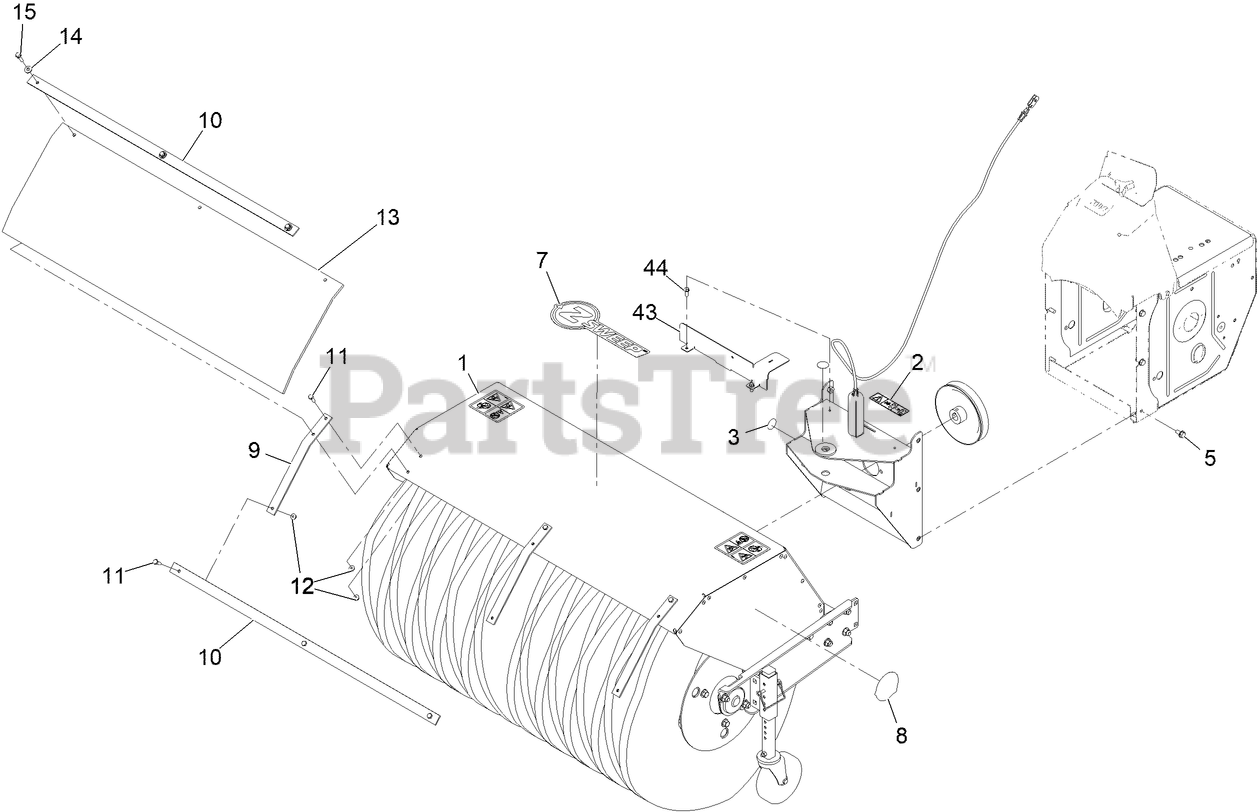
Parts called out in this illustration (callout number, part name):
1	Mb Broom
2	DECAL-COVER, MISSING
3	DECAL-GREASE
5	SCREW-HWHTF
7	DECAL-Z-SWEEP LOGO
8	Decal-Z-Logo
9	STRAP-SUPPORT, DEFLECTOR
10	STRAP-SUPPORT, BROOM DEFL
11	SCREW-HH
13	DEFLECTOR-BROOM
14	WASHER-FLAT
15	SCREW-HHF
43	PLATE-COVER
44	SCREW-HWH
